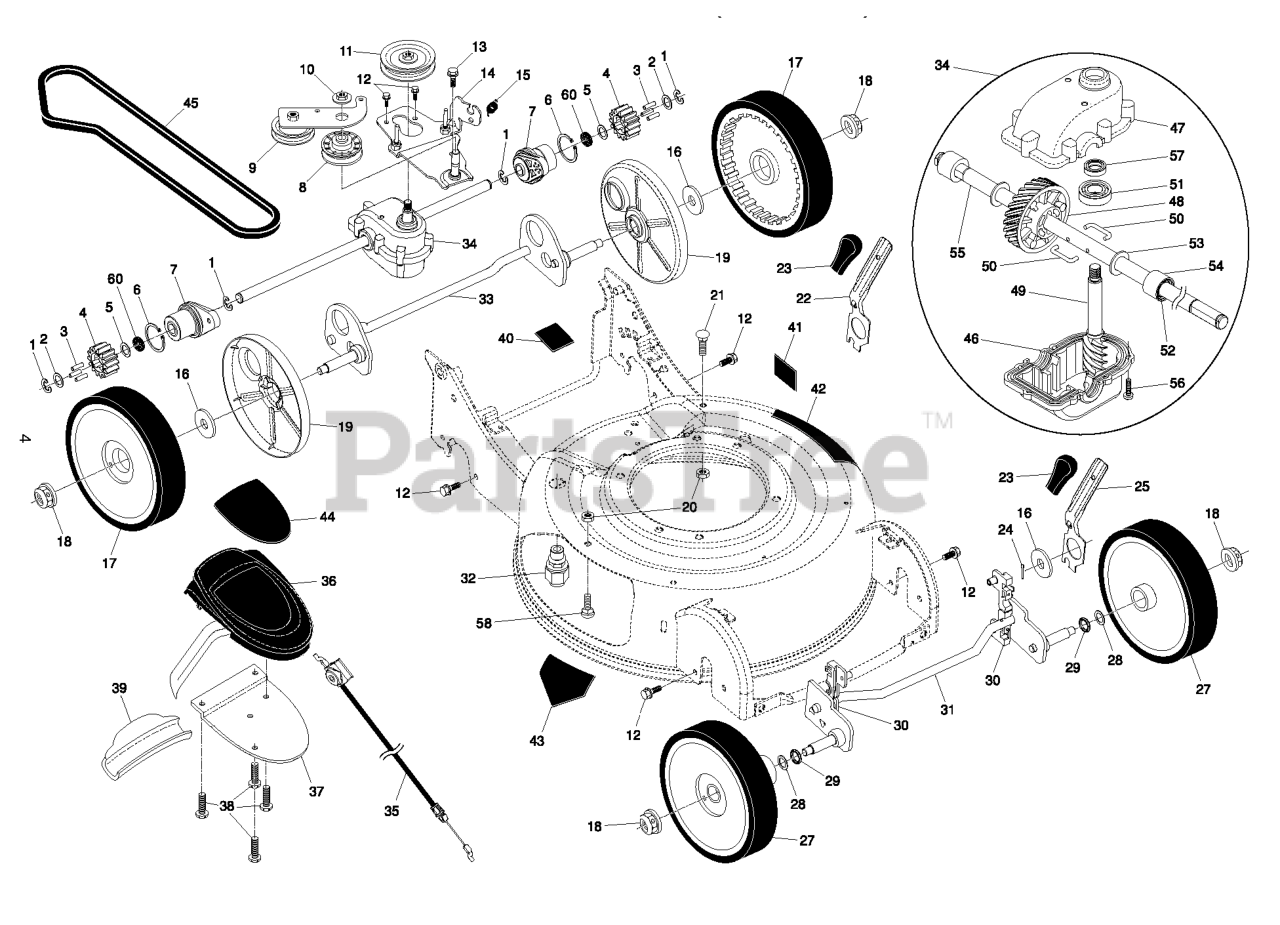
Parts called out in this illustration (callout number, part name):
1	E-RING 7/16 RE
3	PAWL.DRIVE.ETCHED
4	PINION.DRIVE.WALK
6	RETAINING RING (2 2)(3 2)
8	PULLEY.IDLER.V-BELT
10	NUT
11	PULLEY.1.PIECE
13	SCREW 14-20 X 5/8
15	SPRING.RETURN
16	WASHER FLUT
17	WHEEL.8X1.75.H3SPK.RAD3.GY.BU3
18	HEX FLANGE LOCKNT
19	COVER.DUST.WHEEL
20	NUT
24	SPRING RETAINER
27	WHEEL & TIRES ASSY, FRONT
28	WASHER.FLAT.1/2
29	O-RING..070X.487.NEOPRENE
30	BUSHING.FRONT.TORQUE.S
36	CONTROL.DR.HV.RGD.GRY/BLU.45CM
37	BRACKET.DRIVE.CONTROL.MOUNT.BL
38	SCREW, PHILLIPS HEAD 10 X 5/8
39	EZ WALK SNAP COVER PLATE
43	DECAL.INTERNATIONL.CUTFINGER
44	DECAL, DRIVE
46	CASE, LOWER
47	GEARCASE.HOUSING
48	GEAR.24.TOOTH.WALK.MOWER
50	WIRE, FORMED (15966)
52	SEAL.OUTPUT.SHAFT
57	SEAL INPUT SHAFT
58	BOLT.CARRIAGE.1/4-20 X 7/8
